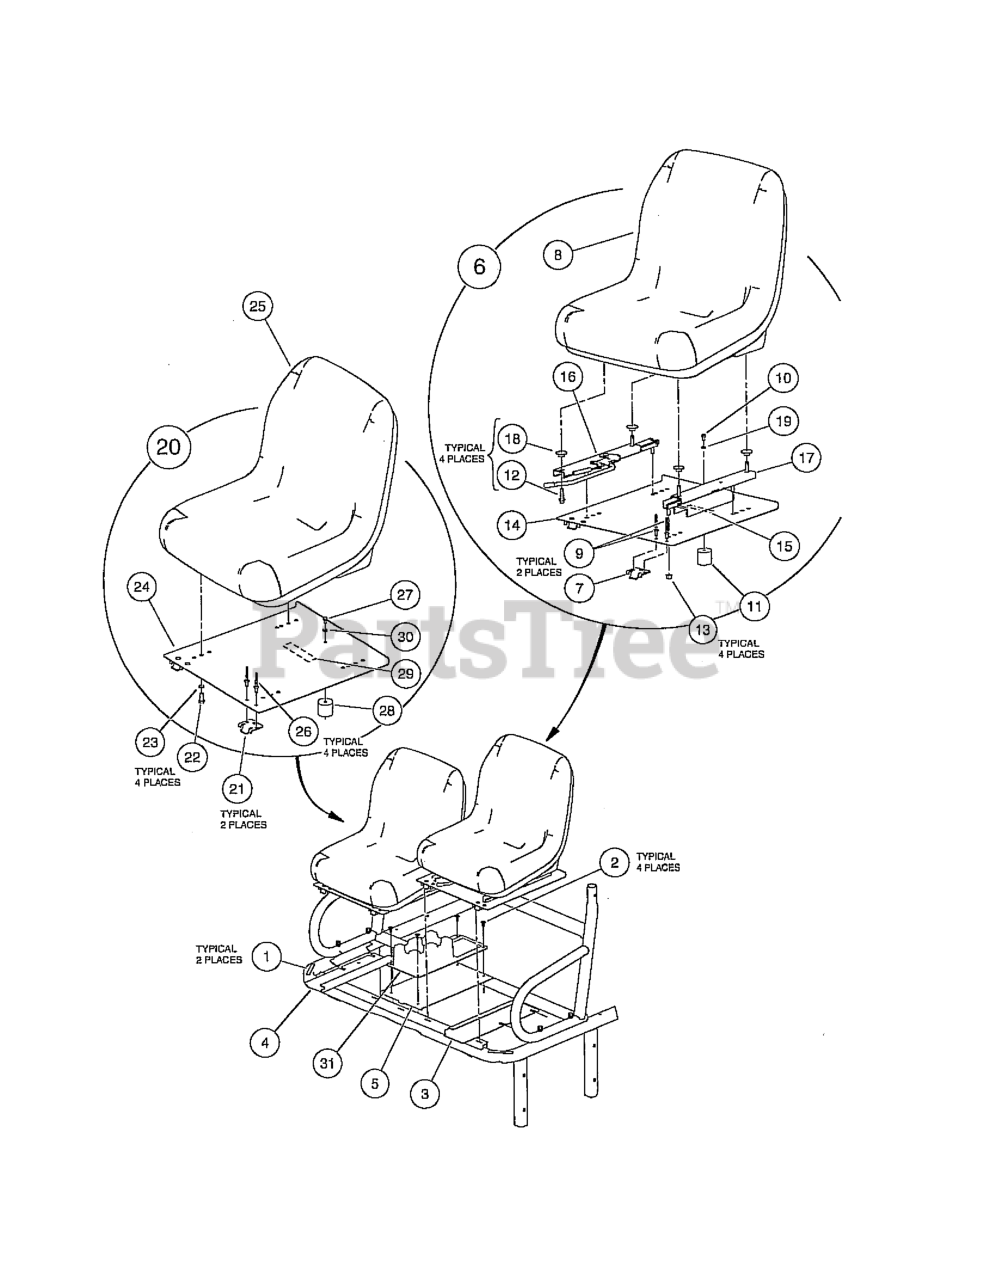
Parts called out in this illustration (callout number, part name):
1	BOX INS.BULK
2	SCREW, TUFLOK PANEL, 1/4
3	CLOSEOUT, DRIVER SIDE
4	CLOSEOUT, PASSENGER SIDE
5	PAN, CENTER, CLOSEOUT
7	HINGE PLATE
8	BUCKET SEAT, GRAY
9	RIVET, 1/4 X .438 BLIND
10	SCREW, 6M-1.00 X 10MM HEX HEAD
11	SEAT HOLDER CUP
12	BOLT - FLANGED HD, M8 X 30.0
13	NUT, M8, ALL METAL LOCK
14	PAN, SEAT, DRIVER ASM
15	DECAL, WARNING HOT SURFACE
16	ADJUSTER, FORE/AFT
17	ADJUSTER, SLIDER
18	WASHER, BELL
19	LOCKWASHER, 1/4 HELICAL SPLIT
21	HINGE PLATE
22	SCREW
24	PAN, SEAT - PASSENGER
25	BUCKET SEAT, GRAY
26	RIVET, 1/4 X .438 BLIND
27	SCREW, 6M-1.00 X 10MM HEX HEAD
28	SEAT HOLDER CUP
29	DECAL, WARNING HOT SURFACE
30	LOCKWASHER, 1/4 HELICAL SPLIT
31	CONSOLE, CENTER, DRINK HLDR
